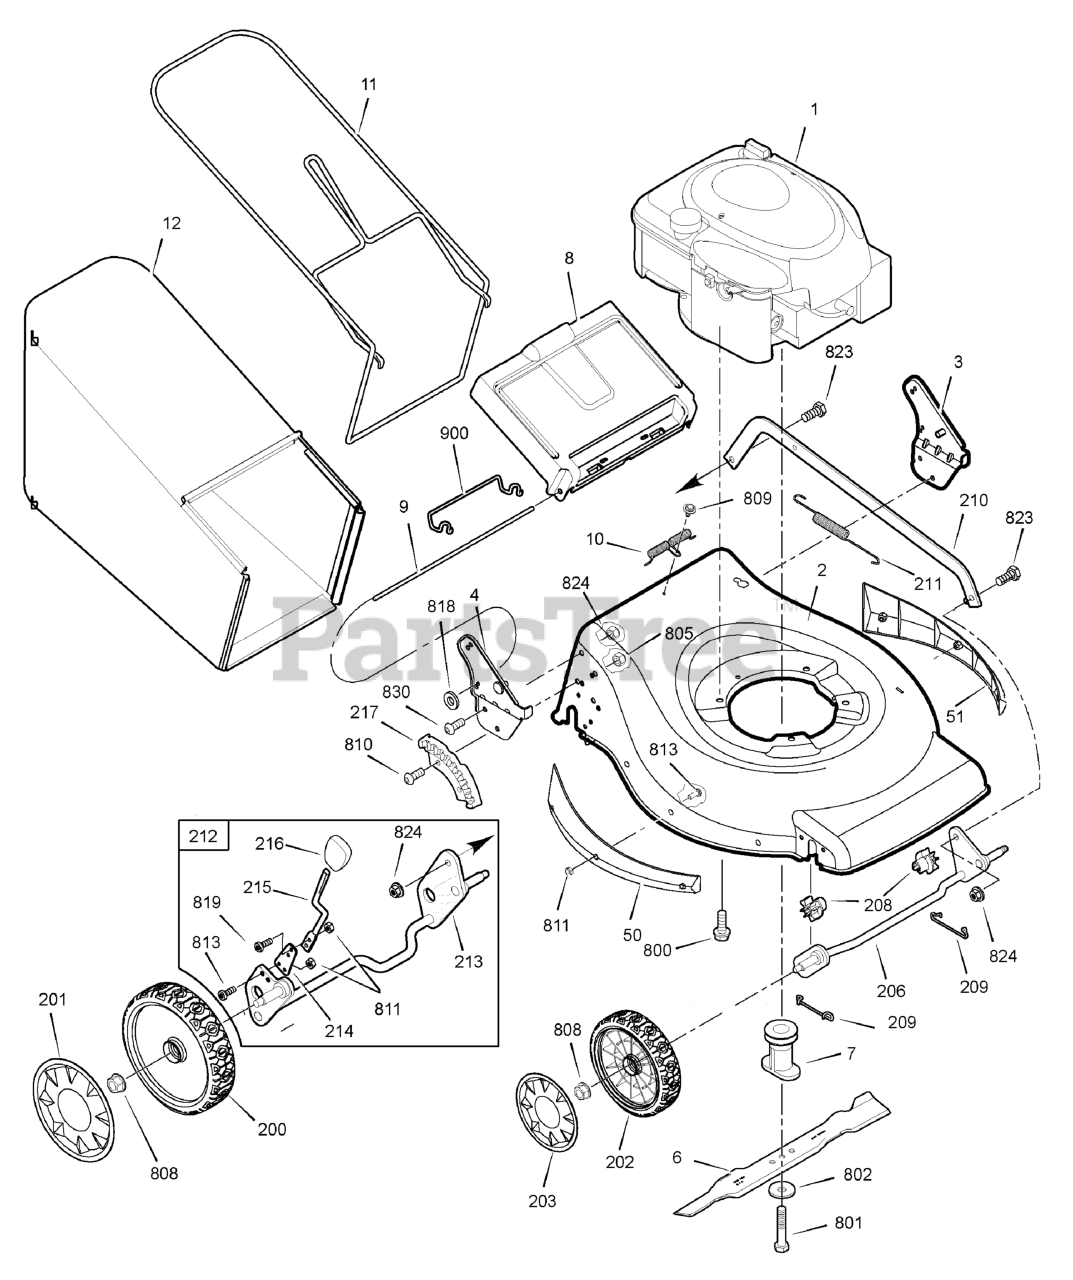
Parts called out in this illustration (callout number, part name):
1	ENGINE
2	MOWER HOUSING
3	BRACKET ASSEMBLY, Left Handle
4	BRACKET ASSEMBLY, Right Handle
6	BLADE, 16 in
7	BLADE ADAPTER ASSEMBLY
8	DOOR, Rear
9	ROD, Rear Door
10	SPRING, Torsion Rear Door
11	FRAME ASSEMBLY
12	BAG ASSEMBLY
50	SIDE GUARD, Right
51	SIDE GUARD, Left
200	WHEEL, Rear
201	HUBCAP, Rear
202	WHEEL, Front
203	HUBCAP, Front
206	CROSSBAR ASSEMBLY, Front
208	BUSHING, Front Crossbar
209	SPRING, Clip Crossbar
210	LINK, Single Lever
211	SPRING, Extension
212	CROSSBAR ASSEMBLY, Rear
213	REAR CROSSBAR
214	SPRING, Adjuster
215	LEVER, Height Adjustment
216	KNOB, Adjuster
217	BRACKET, Height Adjuster
800	SCREW, Hex Head, 3/8-16 x 1
801	BOLT, Blade, 3/8-24 x 2
802	WASHER, Belleville
805	NUT, Nylock, M8 x 1-1/4
808	NUT, Flange, 3/8-16
809	SCREW, Self Tap, #10-16 x 1/2
810	BOLT, Hex Key Head
811	NUT, Nylock
813	SCREW, Torx Head, M5 x .8 x 14mm
818	NUT, Speed
819	SCREW, Torx Head, M5 x .8 x 12.5mm
820	SCREW, Tap, #10 x 1-1/4
823	BOLT, Shoulder, 5/16-18 x 1
824	Nut, Flange, 5/16-18
830	SCREW , 5/16-18 x 3/4
900	SPRING CLIP, Rear Door
1000	DECAL KIT
1001	MANUAL KIT
